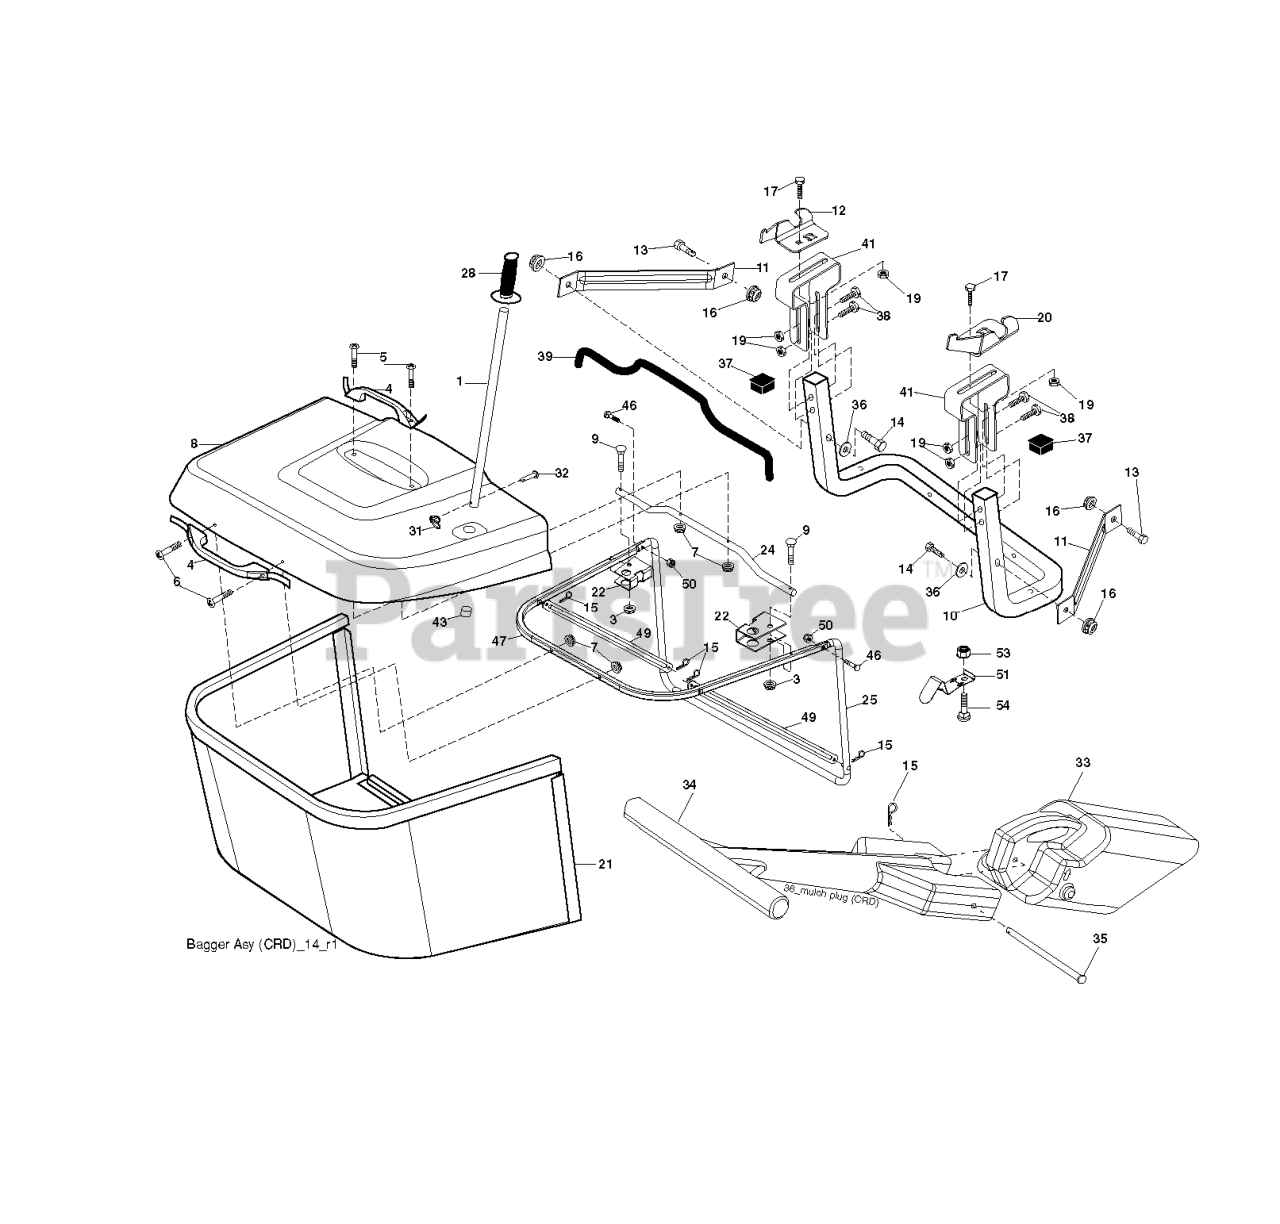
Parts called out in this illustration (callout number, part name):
1	TUBE HANDLE
3	NUT T
4	HANDLE.BAGGER.W/LVRS.BLK.CRD
5	SCREW.PAN.HEAD
6	REPL BY 532 75 00-29
8	COVER.PNT.BGR.CRD.WSLOTS.MS668
9	Bolt Carriage 1/4-20 x 2.25d x Gr.5
10	TUBE
11	BRACKET.SUPPORT.UPPER.BAG.CRD
12	BRKT PIVOT
14	BOLT-HEX EAK
15	RETAINER-SPRNG RB
16	NUT LOCK FLG 3/8-16 UNC
17	RP BOLT 5/16-18 X3/4 ZN/YEL GR
19	NUT LOCK HEX FLANGE 5/16-18
20	BRKT.PIVOT.RH.CRD
21	BAGGER.ASM.CRD.2007
22	BRKT.SIDE.BAG.CRD
24	TUBE.PIVOT.BAG.CRD.BLACK
25	PIPE
28	GRIP.HANDLE.BLACK
31	RETAINER CLIP
32	RIVET,DRILLED
33	MULCH PLUG, CTH150
34	HANDLE.MULCHER.92.CRD (2 2)
36	WASHER
37	Plug Support Bagger CRD
38	BOLT.5/16-18X2.5
39	SEAL.BAGGER.CRD
41	BRKT.VERT.ADJ.BAGGER.CRD
43	PLUG, TUBING END
46	BOLT.CARRIAGE.5/16-18
47	PIPE
49	ROD
50	NUT.71038.31-18.HEX.NYLOCK
51	LATCH
53	NUT
54	BOLT
